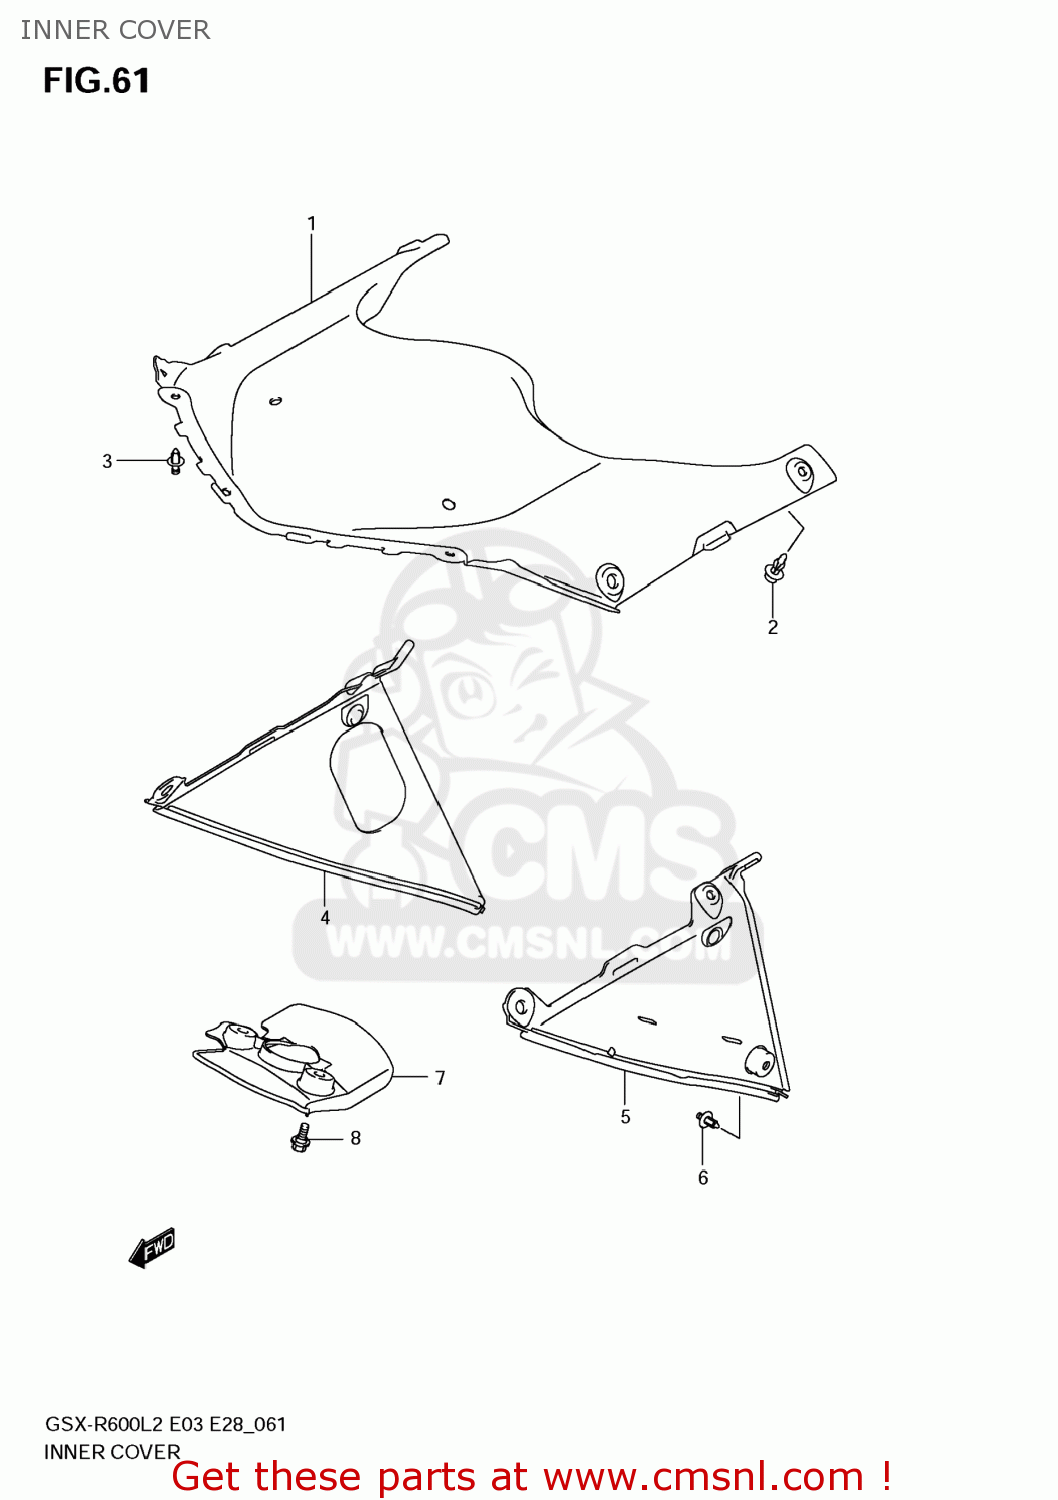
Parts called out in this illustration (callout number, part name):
1	COVER,BODY COWLING
2	CLIP(BLACK)
3	CLIP(BLACK)
4	COWLING,UNDER INNER,R
5	COWLING,UNDER INNER,L
6	CLIP
7	COVER,LWR BRACKET
8	BOLT(6X12)
